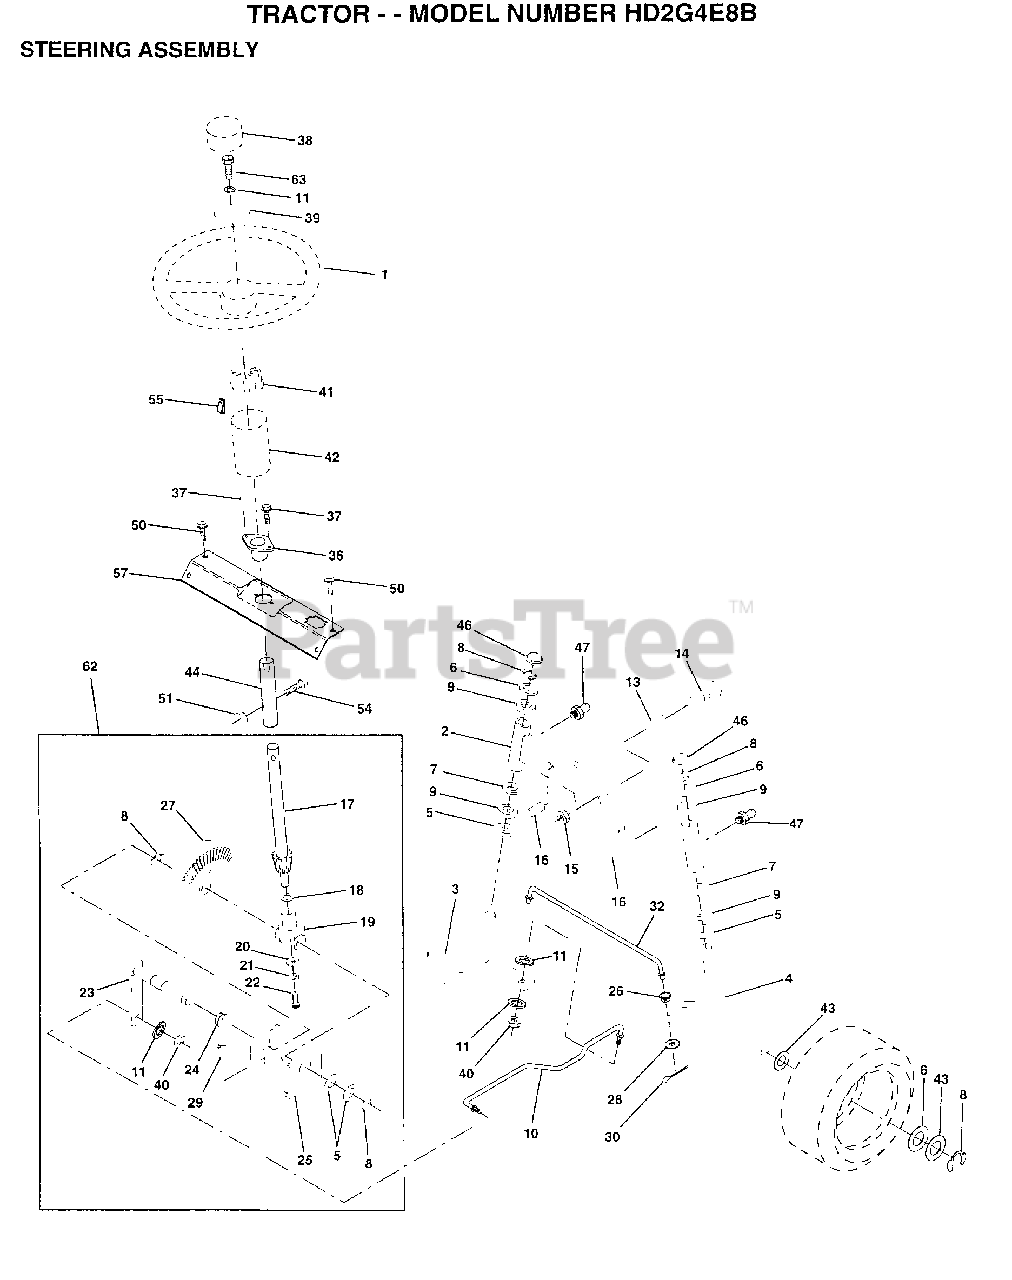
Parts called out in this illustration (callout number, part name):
1	WHEEL STR AYP BLK
2	AXLE ASM FRONT
3	SPINDLE LH
4	SPINDLE RH
5	WASHER .T
6	WASHER
7	WASHER
8	RING
9	COL. SRTG. BEAR.
11	LOCKWASHER
13	BEARING
14	BOLT HEX 5/8-11
15	"NUT-LOC,FLANGE LT"
16	AXLE PIN
17	SHAFT ASM STEERIN
18	THRUST WASHER
19	SUPPORT.SHAFT
21	LOCKWASHER
22	SCREW.SCKTHD.CAP
24	NYLINER T
25	"BRKT,STEERING"
26	BUSHING.DRAGLINK
27	GEAR SECTOR
28	WASHER
29	SCREW
30	COTTER PIN
32	TIE ROD
37	"SCREW-TT,10-32 FL"
38	CAP STEER AYP
39	WASHER T
41	ADAPTER LT
42	BOOT SHAFT STEER
43	WASHER
44	SHAFT EXT STEERIN
46	CAP
47	ZERK M
50	SCREW HEX CRT
51	NUT
54	BOLT
55	CLIP TINNERMAN
57	SUPPORT SHAFT STR
63	BOLT
